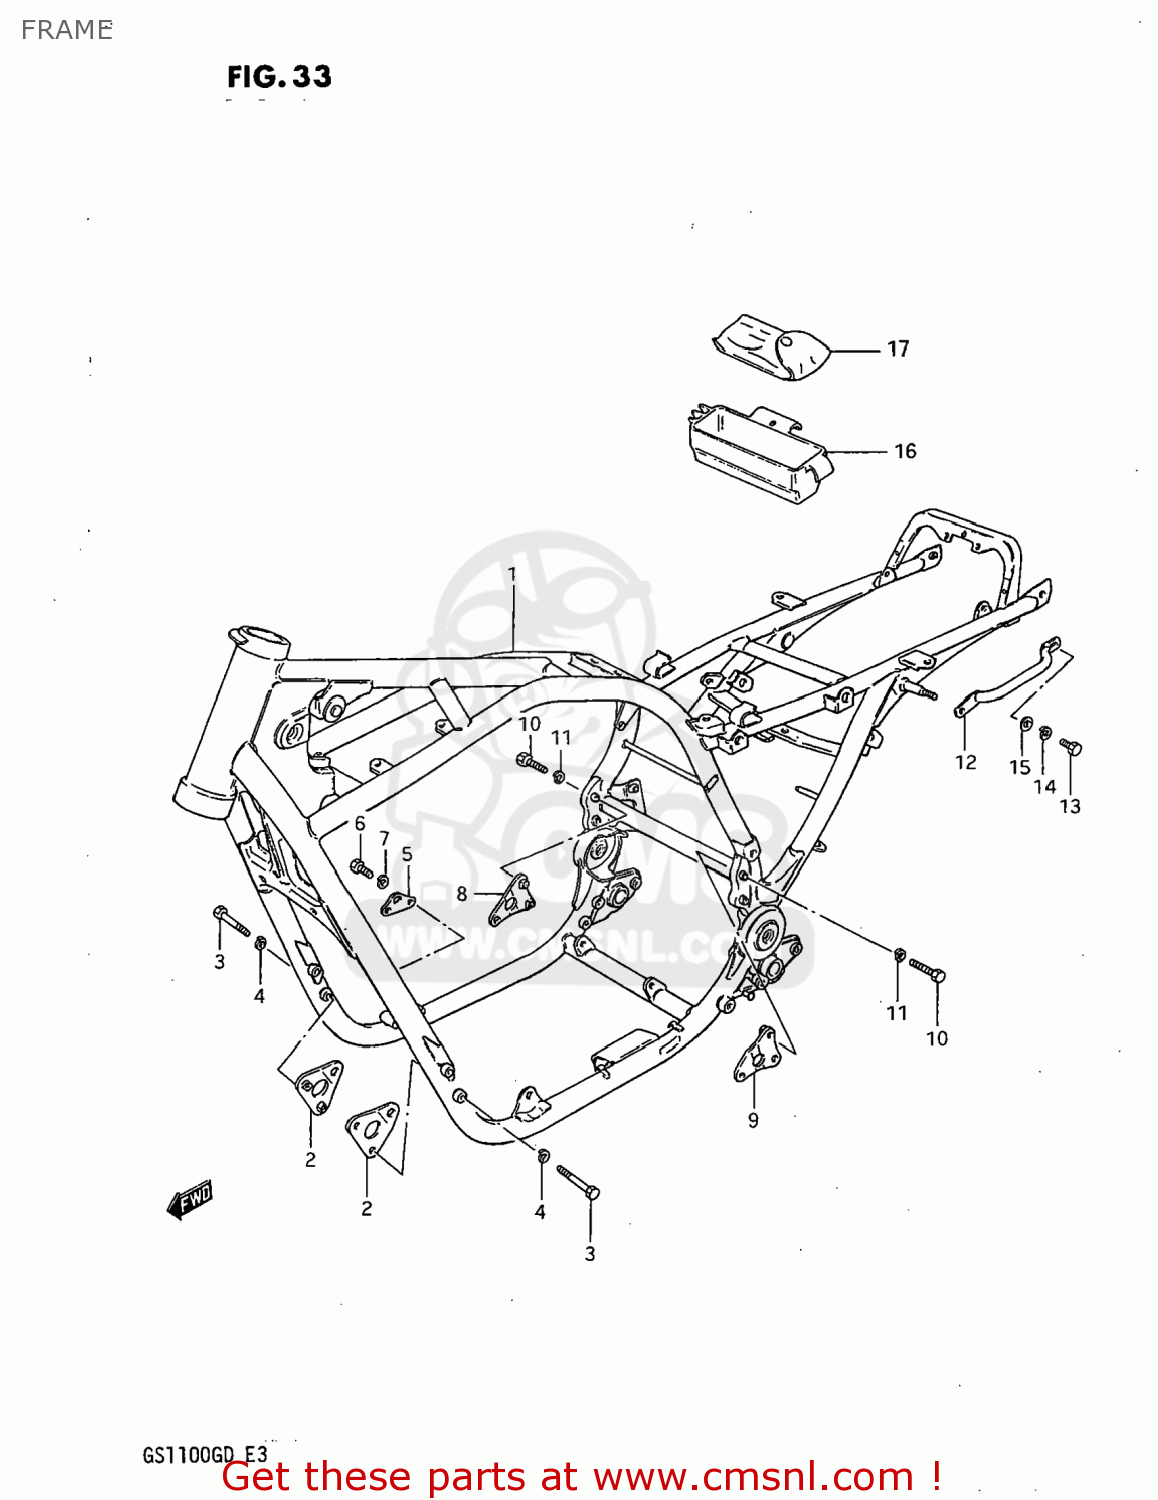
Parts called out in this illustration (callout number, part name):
1	FRAME
2	PLATE,ENGINE MOUNTING
3	BOLT
4	LOCK WASHER
5	PLATE,ENGINE MOUNTING
6	BOLT
7	LOCK WASHER
8	PLATE,ENGINE MOUNTING
9	PLATE,ENGINE MOUNTING
10	BOLT 8X40
11	LOCK WASHER
12	GRIP,FRAME HANDLE
13	BOLT
14	LOCK WASHER
15	WASHER
16	HOLDER,TOOL
17	TOOL SET
